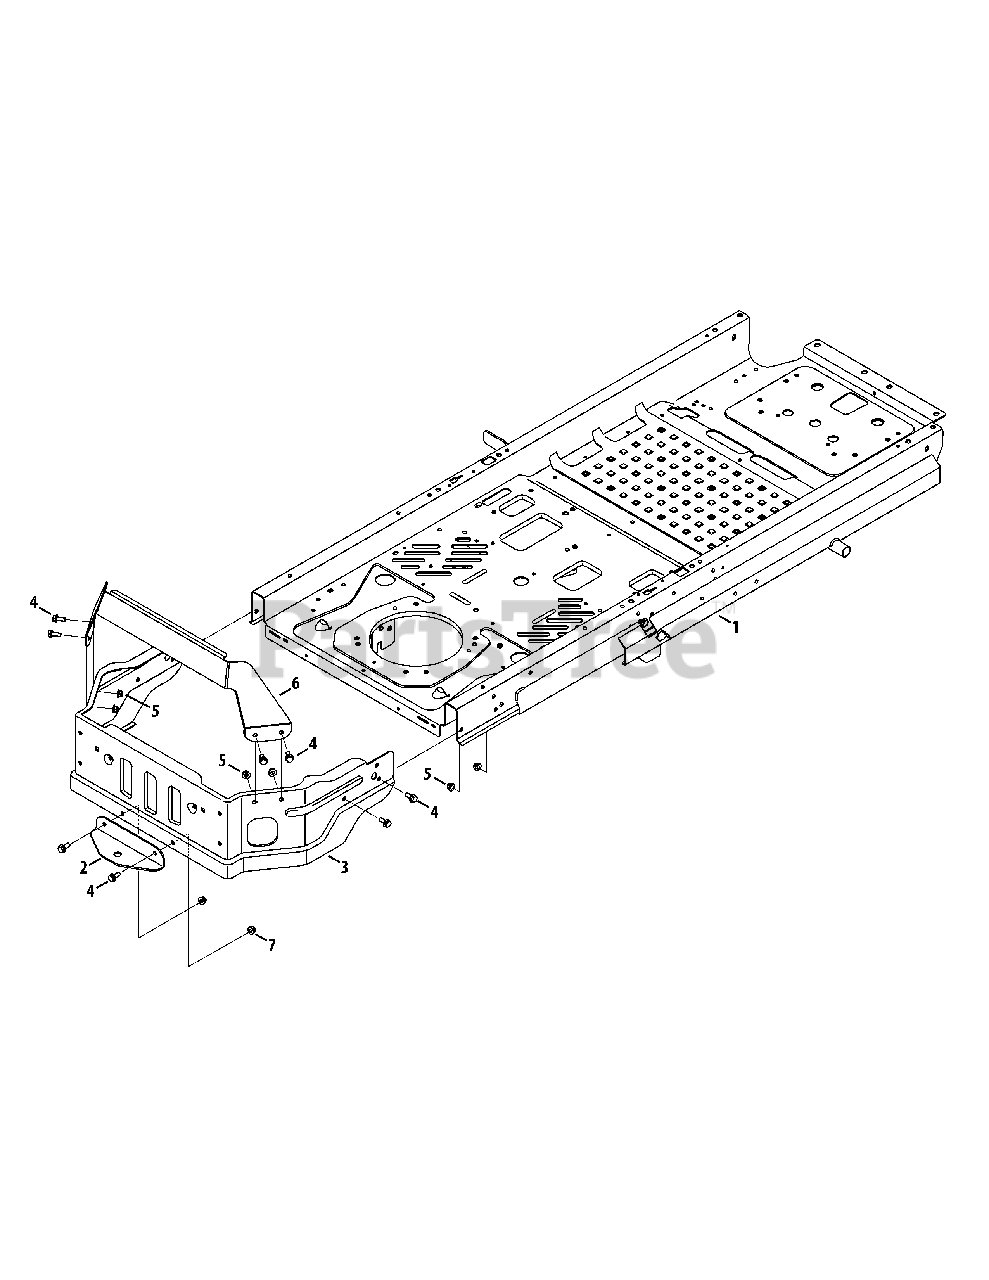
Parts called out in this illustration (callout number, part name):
1	Frame Assembly
4	Screw, 5/16-18, Hexflange
5	Flange Lock Nut, 5/16-18
6	Upper Bumper Bracket
7	Flange Counter Lock Nut, 5/16-18
